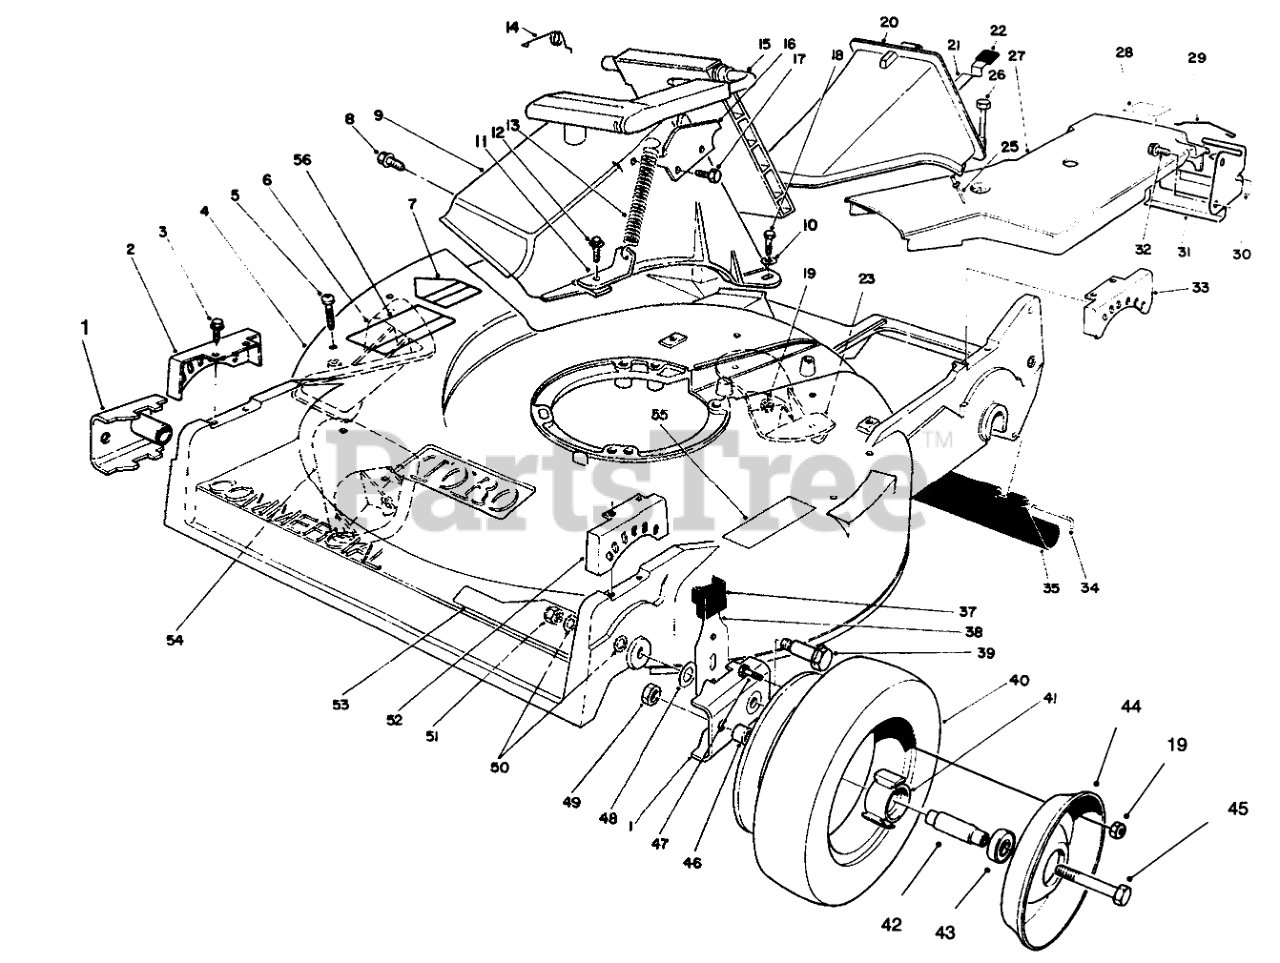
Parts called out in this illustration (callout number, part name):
1	ARM-PIVOT, FRONT
2	QUADRANT-FRONT, RH
3	SCREW-HWHTF
4	Housing-Commercial (Incl. Ref. #5-7, 23, & 54-56)
5	SCREW-HWHTF
6	KICKER-RH
7	DECAL-DANGER
8	SCREW AND WASHER ASM
9	DISCHARGE TUNNEL
10	WASHER-FLAT
11	BRACKET-SPRING
12	SCREW-HWH
13	SPRING-DOOR
14	RETAINER-DOOR
15	DOOR ASSEMBLY
16	DOOR LATCH PLATE
17	SCREW-PLASTITE
18	SCREW-HH
19	NUT-LOCK, NI
20	Plug-Discharge (Incl. Ref. #21, 22, & 25)
21	LATCH-PLUG, DISCHARGE
22	GRIP-LATCH
23	KICKER-REAR
25	RIVET-HEAD, FLAT
26	SCREW-HHFTF
27	BELT COVER (MACHINED)
28	LABEL-GREASE
29	RETAINER-CABLE
30	DECAL-POSITION, GEAR
31	BRACKET-ADJUSTMENT, TRACTION
32	SCREW-HWHTF
33	QUADRANT-REAR, LH
34	ROD-SHIELD
35	Shield-Rear Safety
37	KNOB-ARM
38	FRONT SPRING ARM ASM
39	BOLT-WHEEL
41	HUB-BEARING
42	SPACER-BEARING
43	BEARING-WHEEL
44	Wheel-Half
45	SCREW-HH
46	SPACER-WHEEL
47	SCREW-HH
48	WASHER-THRUST
49	NUT-LOCK, CONE
50	WASHER
51	NUT-LOCK
52	QUADRANT-FRONT, LH
53	DECAL - DECK
54	KICKER-FRONT
55	DECAL-INSTRUCTION, SAFETY
56	DECAL - DANGER, COVERS
